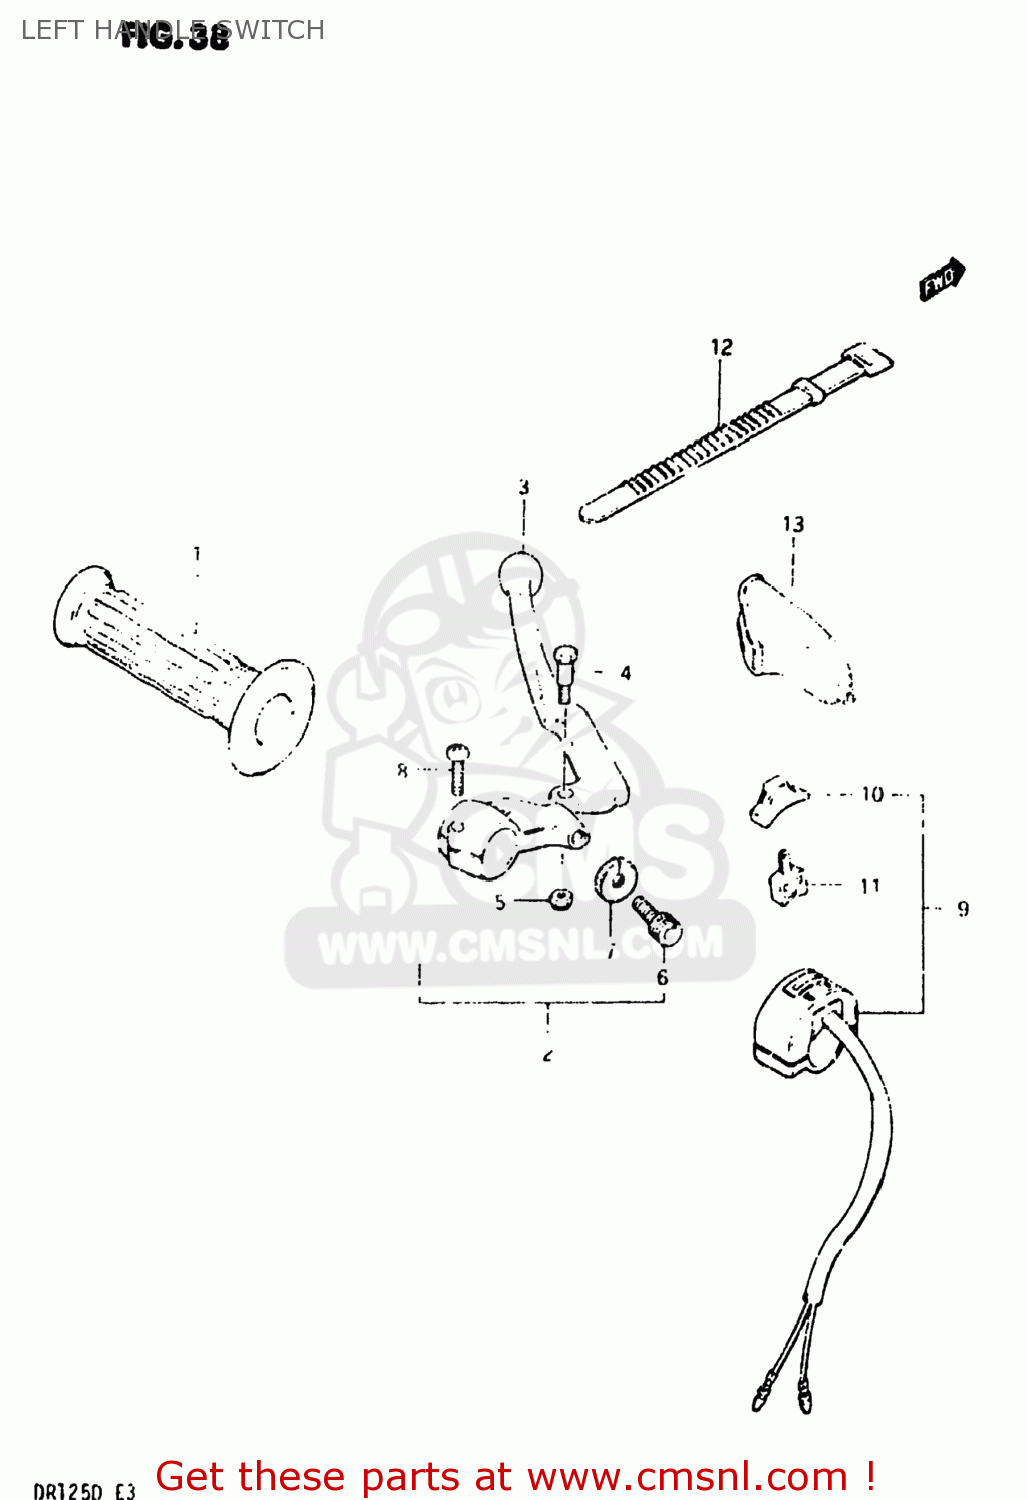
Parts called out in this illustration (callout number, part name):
1	GRIP,L
2	LEVER ASSEMBLY,CLUTCH
3	LEVER,CLUTCH
4	BOLT,LEVER
5	NUT 6MM
6	ADJUSTER,CABLE
7	NUT,CABLE ADJUSTER
8	SCREW 6X70
9	SWITCH ASSY,LIGHTING
10	KNOB,LIGHTING & DIMMER
11	BLOCK,LIGHTING/DIMMER
12	CLAMP(L:120)
13	COVER,CLUTCH LEVER
